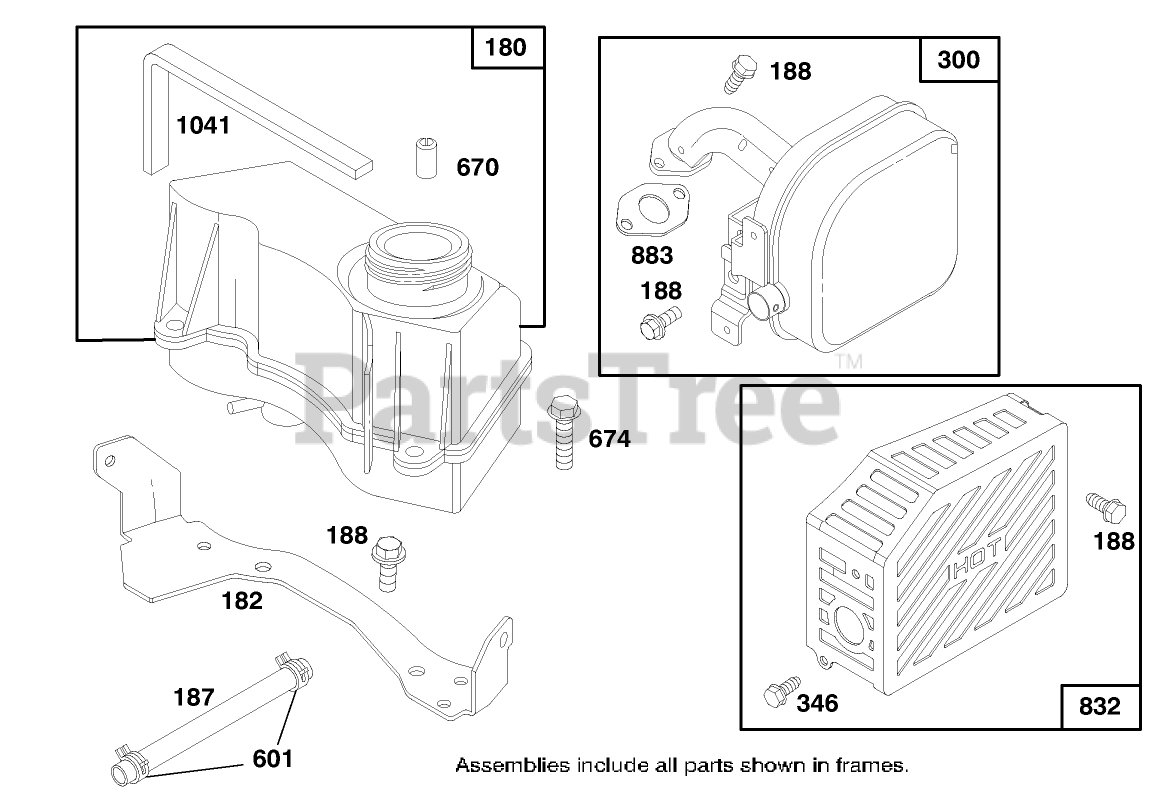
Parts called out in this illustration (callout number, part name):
180	TANK ASSY - FUEL
300	MUFFLER - EXHAUST
670	SPACER
674	SCREW - HEX HEAD
